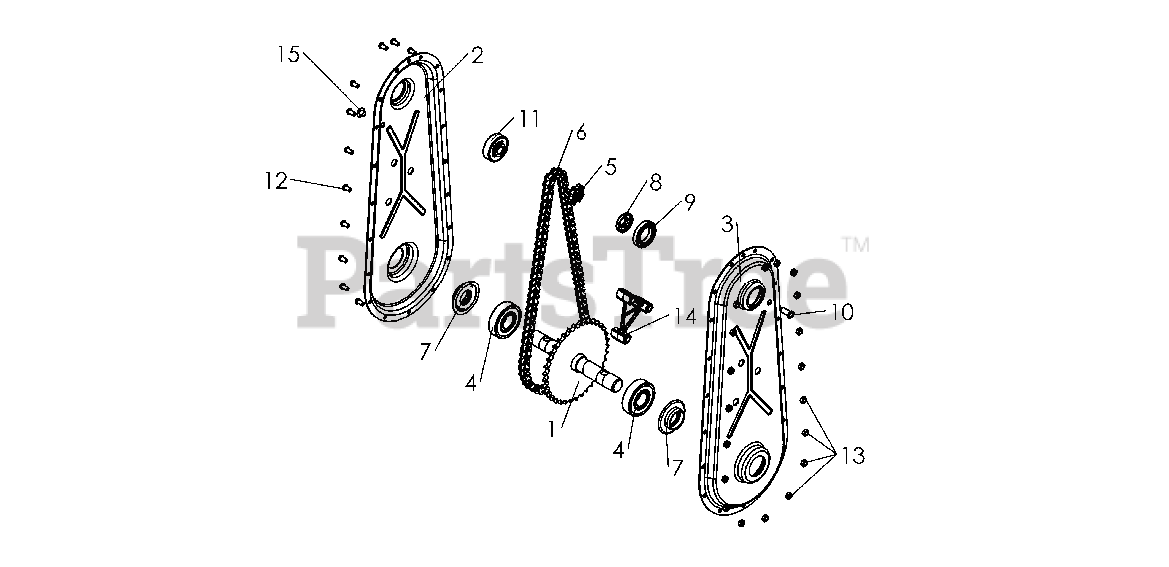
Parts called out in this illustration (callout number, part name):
4	BEARING
5	PINION
9	BALL BEARING
13	Blocking nut M 6 Z
